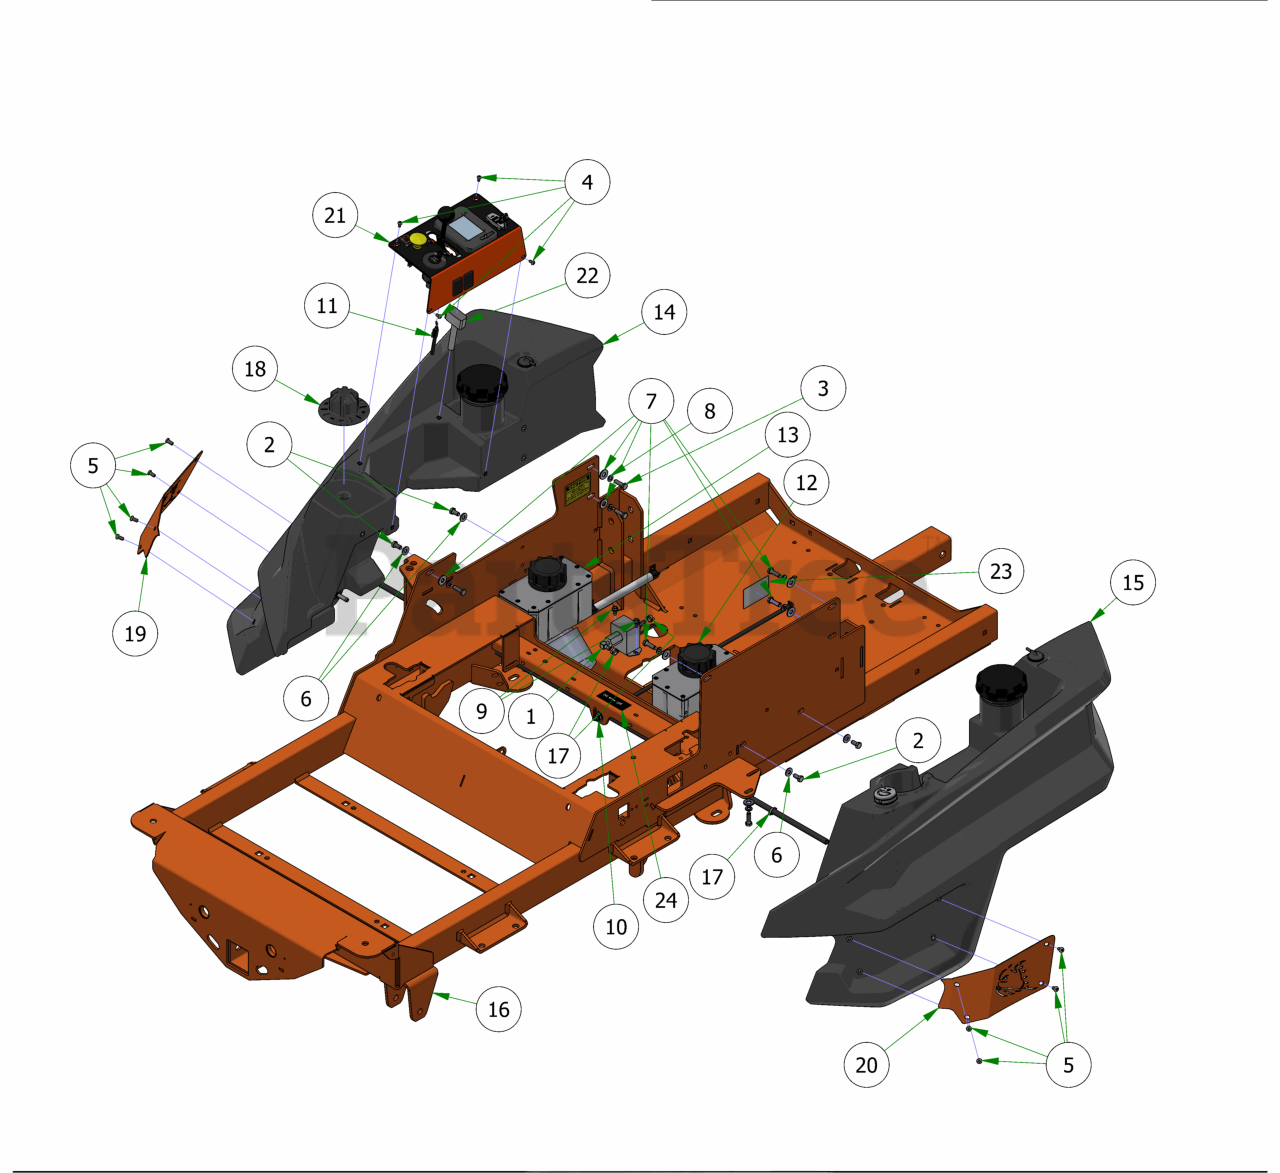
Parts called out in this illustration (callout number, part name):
2	5/16-18 x 5/8 Hex Bolt
3	5/16-18 X 1 HEX CAP SCREW (GR.5) ZINC
4	10-32 X 3/8 BUTTON SOCKET CAP SCREW 18-8 STAINLESS STEEL
5	1/4-20 X 1/2 BUTTON SOCKET CAP SCREW 18-8 STAINLESS STEEL
6	1/4 USS FLAT WASHER (3/4 OD) ZINC
7	5/16 USS FLAT WASHER (7/8 OD) ZINC
8	5/16 SPLIT LOCKWASHER ZINC
9	1/4-20 X 1/2
10	2023 Rebel Rogue Renegade Fuel Line for Kohler
11	Outlaw Throttle Cable
12	LH Rogue Hydro Tank Assy
13	RH Rogue Hydro Tank Assy
14	2019 Right Rebel, Rogue, Renagade Fuel Tank (GAS)
15	2019 Left Rebel, Rogue, Renegade Fuel Tank (GAS)
16	2019 Renegade Gas Frame - Powdercoated
17	2 EAR CLAMP 12.5mm-15mm
18	2019 Deck Height Dial
19	2019 Outlaw Fuel Tank Insert - Right
20	2019 Outlaw Fuel Tank Insert - Left
21	Renegade Control Panel Assembly
22	2019 LCD Panel Harness-Renegade
23	Hydraulic Decal
24	R-Series Shut Off Valve Decal
